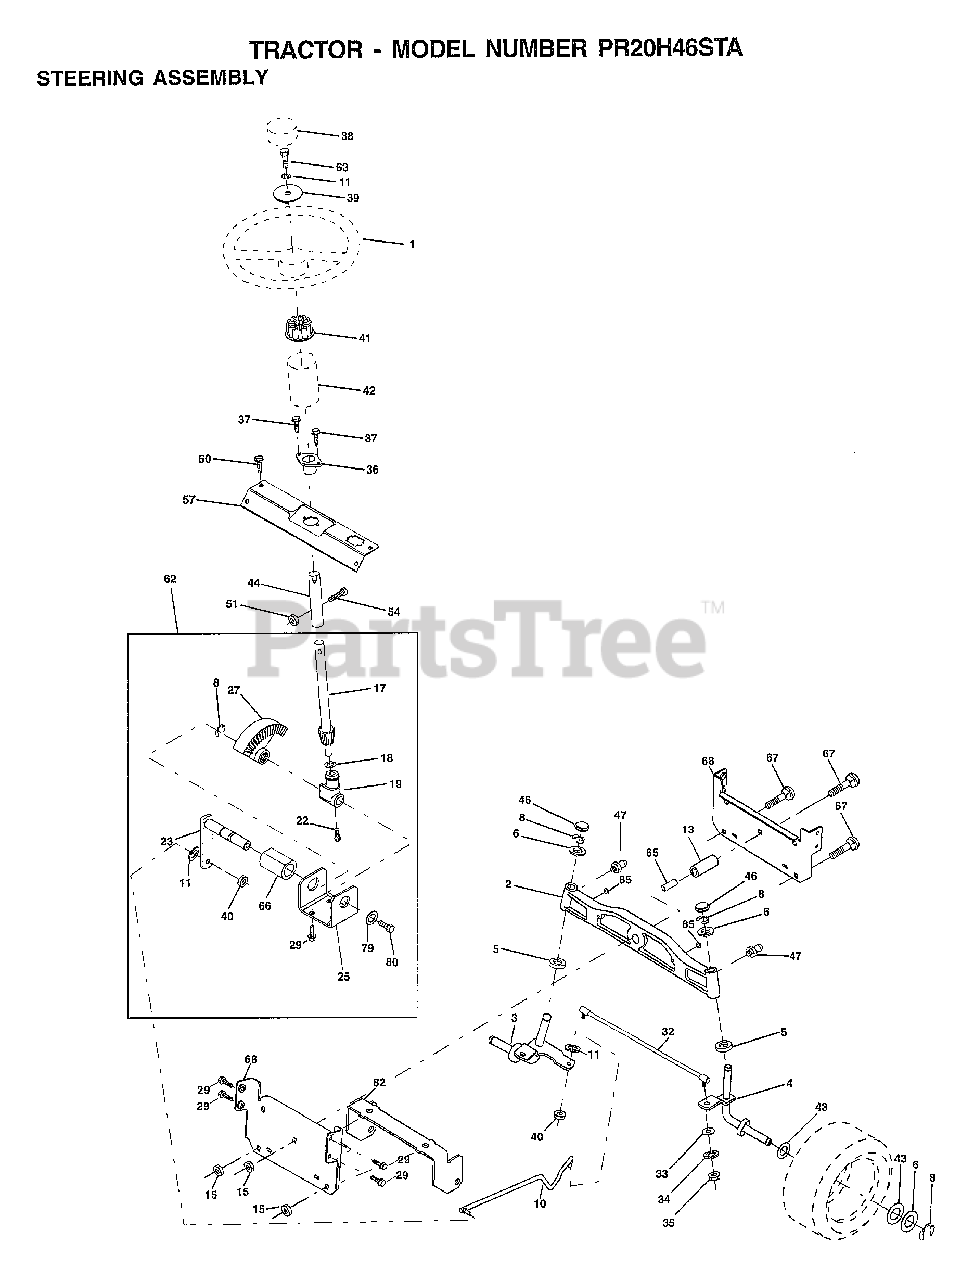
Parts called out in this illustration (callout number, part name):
1	WHEEL.STEERING
2	AXLE ASSY
3	SPINDLE ASM
4	SPINDLE ASM
5	WASHER .T
6	WASHER
8	RING
10	LINK DRAG
11	LOCKWASHER
13	SPACER BEARING
15	NUT.HXFLG.LOCK.
17	SHAFT ASM STEERIN
18	THRUST WASHER
19	SUPPORT.SHAFT.STEER
22	SCREW.HX.WSH.HD
23	SHAFT.ASM.PITMAN
25	BRKT-STEERING
27	GEAR SECTOR
29	SCREW
32	ROD TIE
33	WASHER M
34	LOCKWASHER
35	CROWNLOCK NUT
36	BUSHING.STR.623
37	"SCREW-TT,10-32 FL"
38	INSERT.CAP.STRG.WH
39	WASHER
40	GRIPCO NUT
41	ADAPTOR.WHEEL.STG
43	WASHER
44	EXT SHAFT STEERIN
46	CAP
47	ZERK M
50	SCREW
51	NUT
54	BOLT
57	SUPPORT SHAFT STR
62	KIT.STEER.ASM
63	BOLT
65	"SPACER BRCAE,AXLE"
66	"BEARING-ARM,PITMA"
67	BOLT RDHD 3/8-16
68	BRACE AXLE
79	WASHER
80	BOLT.HX.NYLON3/8-16X3/
82	BRKT SUSP CHASSIS FRT
85	XMAS TREE FASTNER
